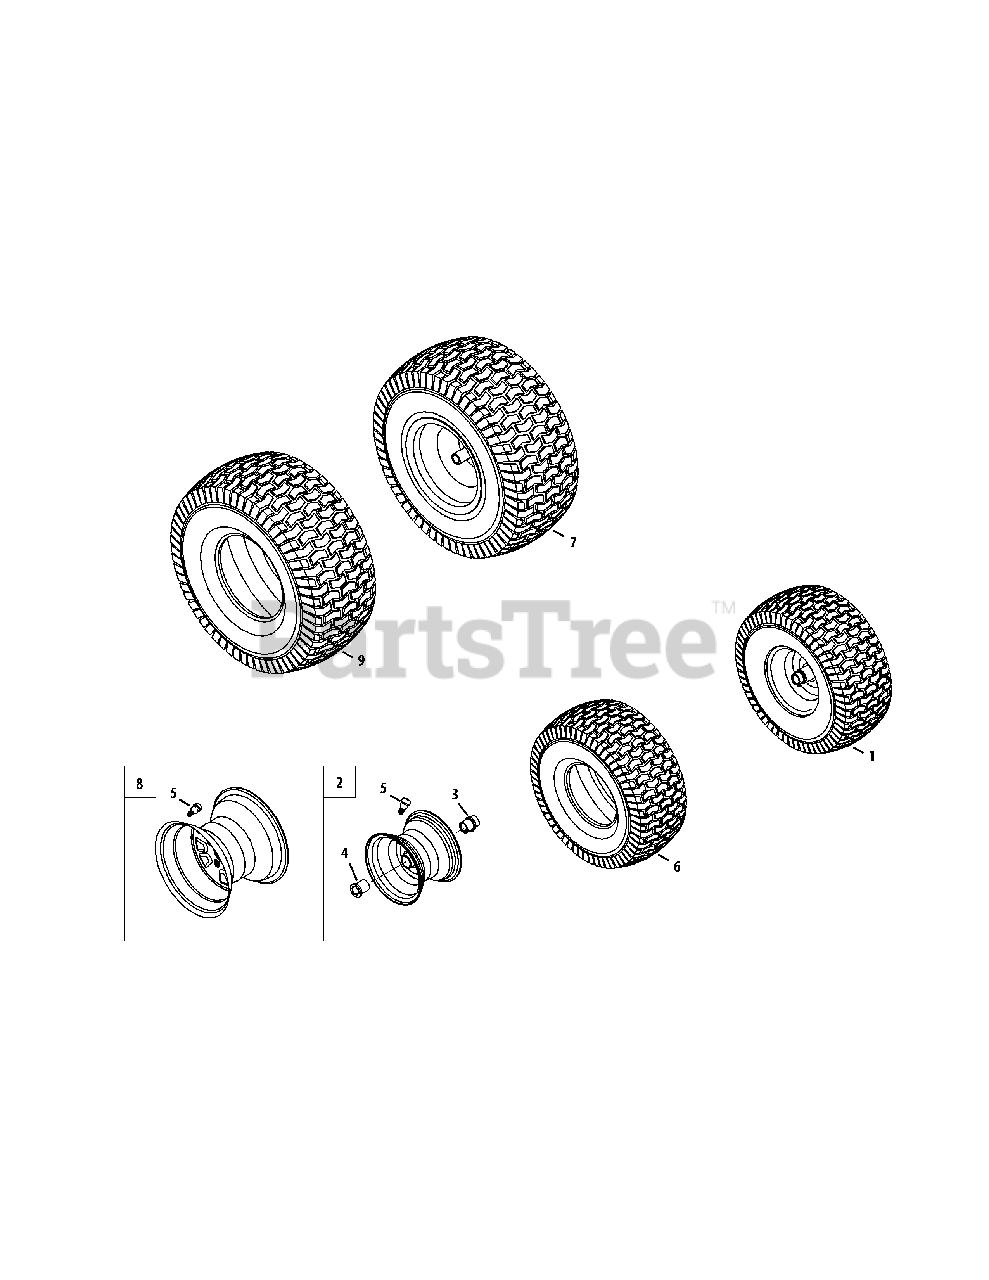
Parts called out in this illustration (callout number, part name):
1	Wheel Ass’y, Complete, 16 x 6 x 5.8
2	Rim Ass’y, 8.0 x 5.3, w/Flange Bearings
3	Bearing, Flange, .760 ID w/ Fitting
4	Bearing, Flange, .760 x 1.00 x 1.20
5	Valve, Tubeless Air
6	Tire, 16 x 6.5 x 8 Sq Shoulder
7	Wheel, Complete, 22 x 9.5 x 12
8	Rim Ass’y, 12.0 x 7.0
9	Tire, 22 x 9.5 x 12 Sq Shoulder
